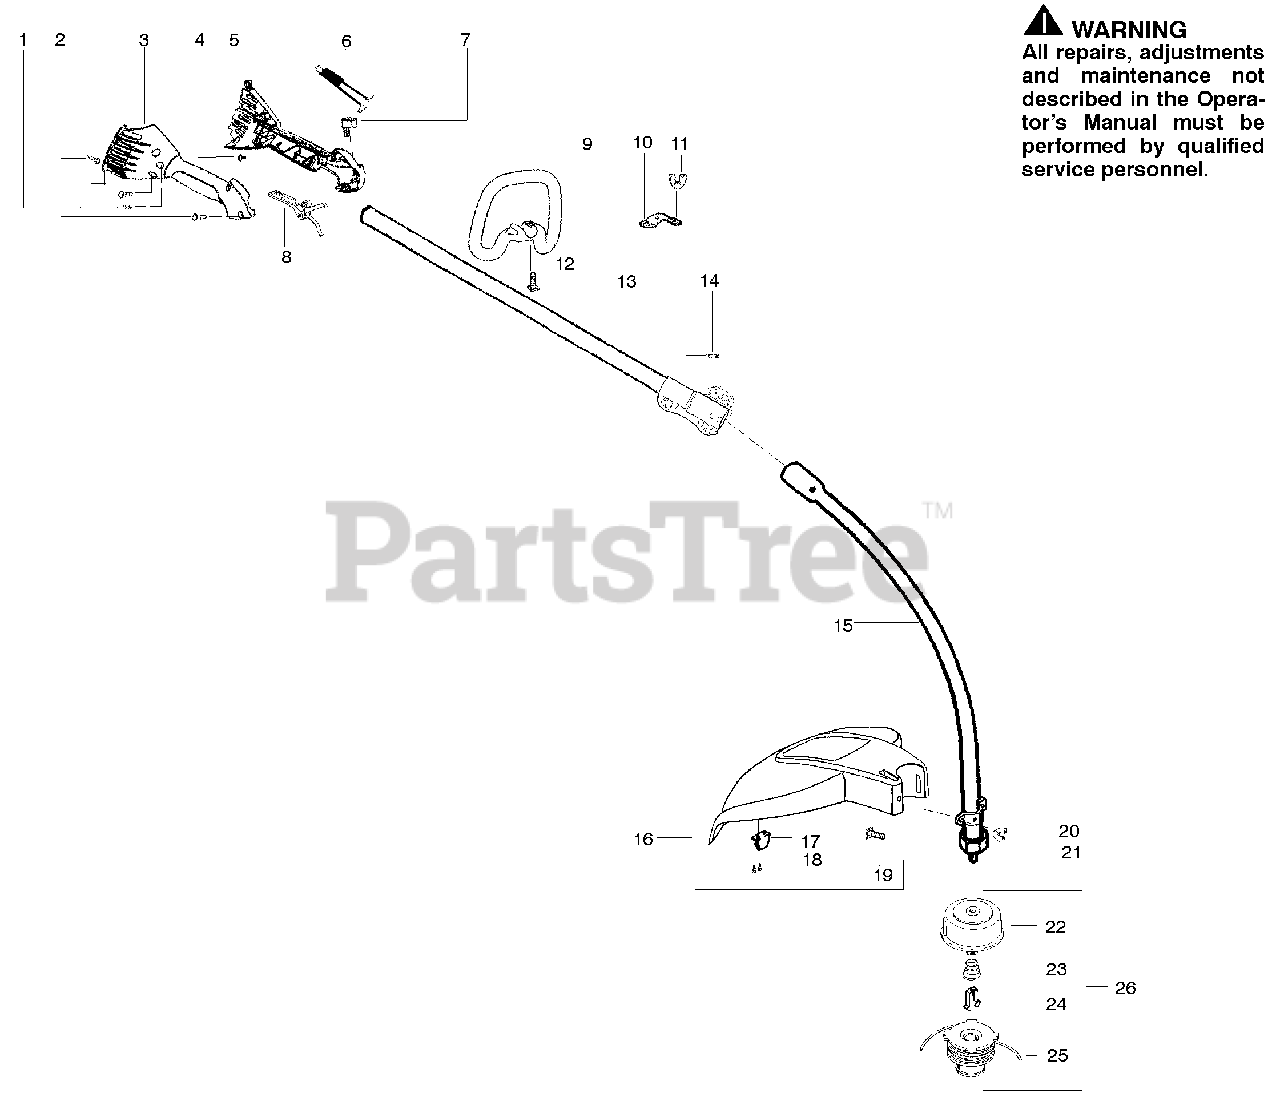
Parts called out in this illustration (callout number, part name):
1	Screw-alignment
3	Hsg.-Throttle right
4	Screw-Cable Retention
5	Hsg.-Left throttle
8	Trigger-Throttle
9	Handle-Assist
10	Clamp-Assist Handle
11	Wingnut
13	Assy-Upper Shaft
15	Assy-Lower Shaft
16	Kit-Shield Assy.
20	Wingnut
22	Assy-Hub/Arbor
23	Spring-Return
24	Retainer-Spool
25	Accy-Wound Spool
26	Accy-Cutting Head
